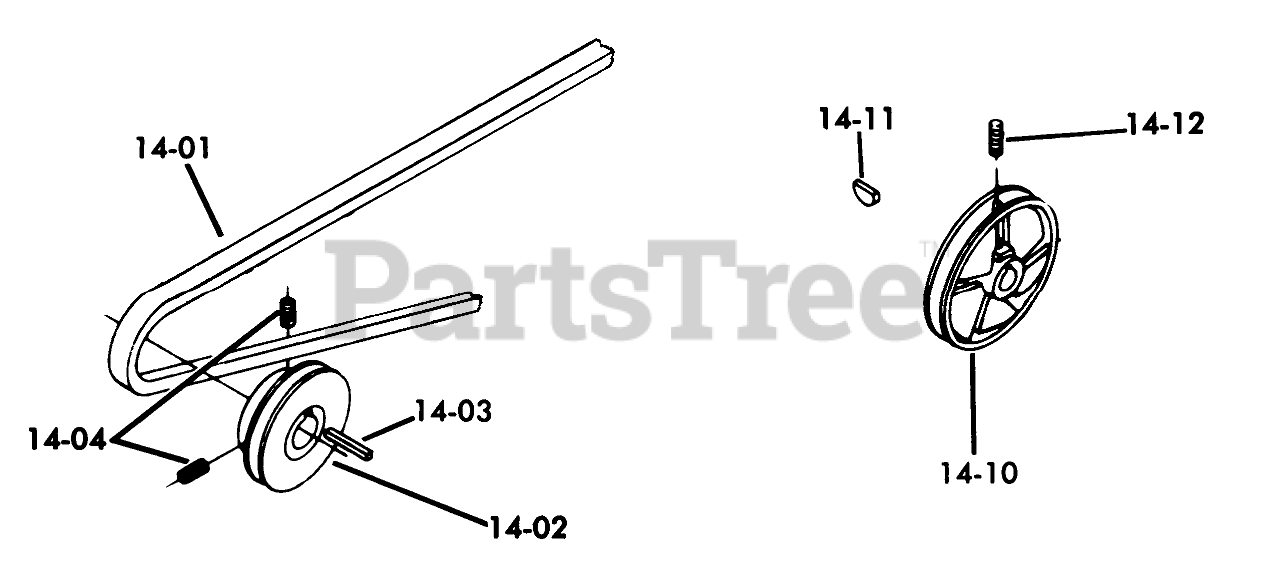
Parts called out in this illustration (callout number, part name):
14-01	V BELT
14-02	PULLEY
14-04	Set Screw
14-10	Pulley Trans
14-11	KEY-HI PRO
14-12	Set Screw
